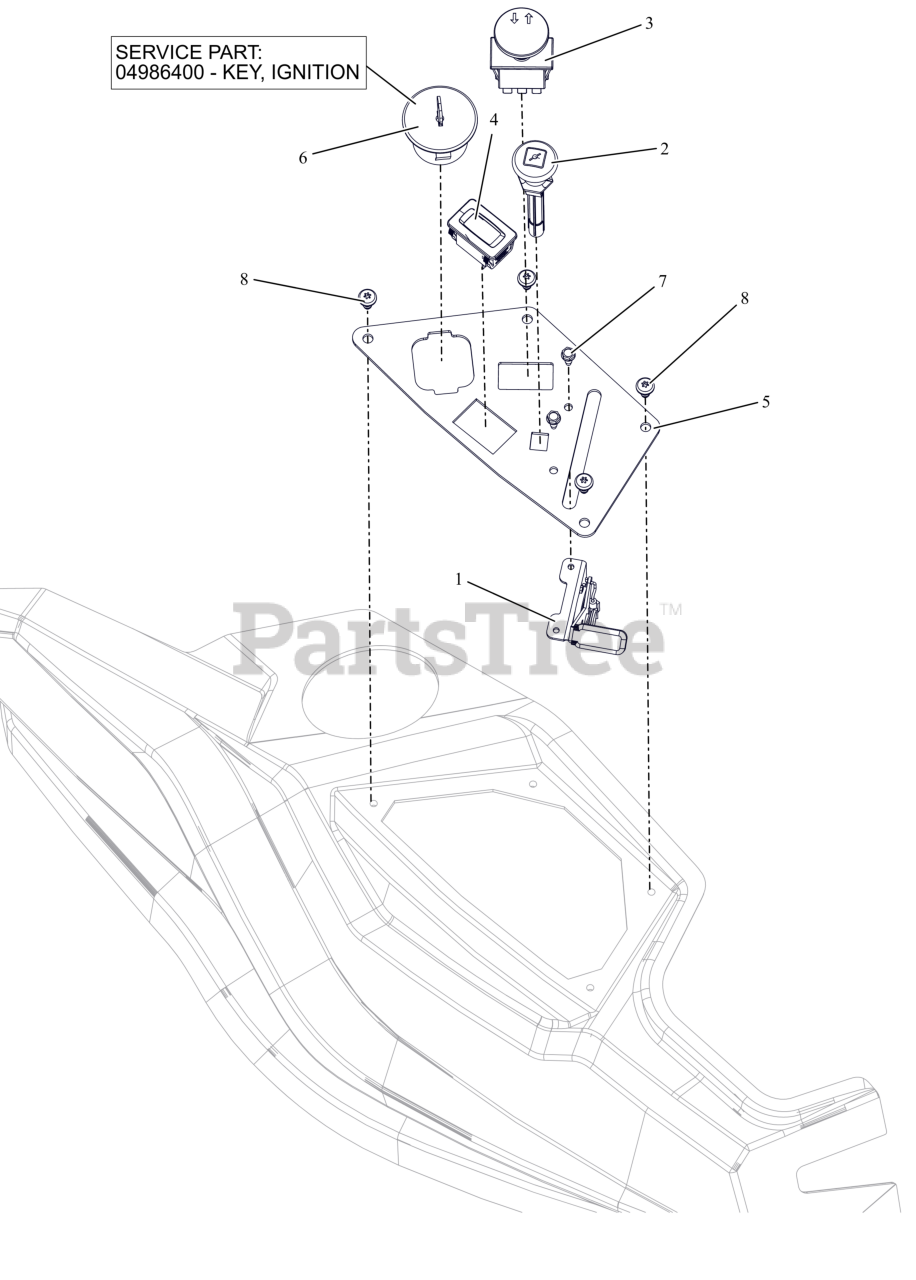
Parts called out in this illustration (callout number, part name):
1	CABLE, THROTTLE
2	CABLE, CHOKE (SNAP IN)
3	SWITCH, CLUTCH (YELLOW)
4	HOUR METER
5	PANEL, CONTROL (ORANGE)
6	KEYSWITCH-IGNITION 3 POS
6	KEY, IGNITION
7	SCR,TAP #10-24X.50 HWH TR ZCC
8	SCR-PAN .25-15X.50 6L H/LZB500
